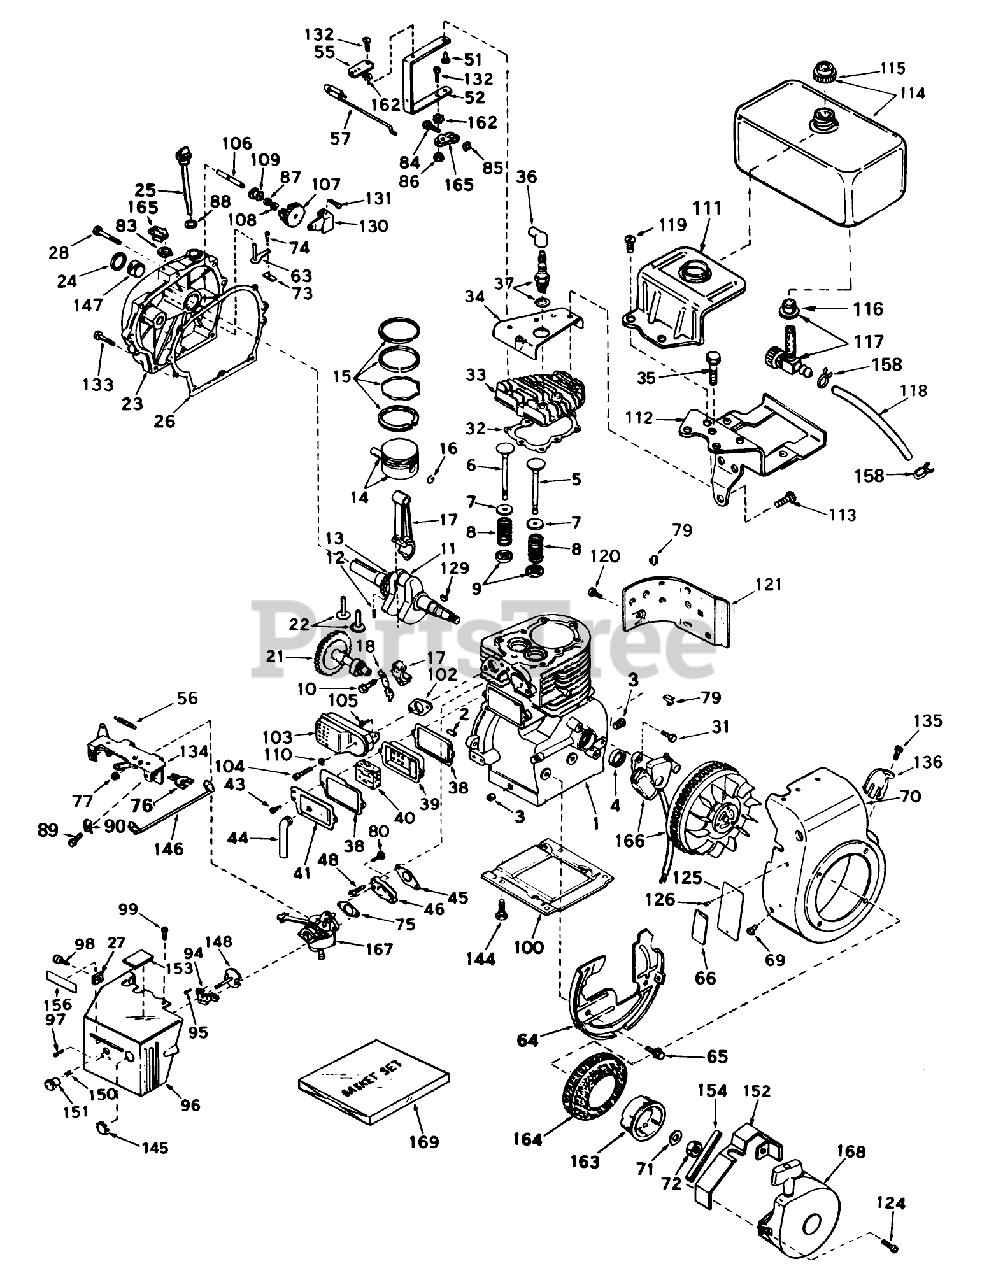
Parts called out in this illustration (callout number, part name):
1	Cylinder Assy. (Incl. Nos. 2, 3 4)
2	Pin-Dowel
3	Plug-Drain, Oil (SQH 1/4-18)
4	Oil Seal
5	Valve, Intake (Standard)(Incl. No. 9)
5	Valve, Intake (1/32" oversize)(Incl. No. 9)
6	Valve, Exhaust (Standard)(Incl. No. 9)
6	Valve, Exhaust (1/32" oversize)(Incl. No. 9)
7	Cap-Spring, Valve
8	Spring-Valve
9	Keeper-Spring, Valve
10	Screw, Hex Hd.
11	Crankshaft Assy. (Incl. Nos. 12 13)
12	Pin, Groove
13	Gear-Crankshaft
14	Piston Pin Assy. (Incl. 2 of No. 16)(Standard)
14	Piston Pin Assy. (Incl. 2 of No. 16)(.010 oversize)
14	Piston Pin Assy. (Incl. 2 of No. 16)(.020 oversize)
15	ORing
15	Ring Set (.010" OS)
15	Ring Set (.020" OS)
17	Rod Assy., Connecting (Incl. Nos. 10 18)
18	Plate, Lock
21	Camshaft
22	Lifter Valve
23	Cover, Cylinder (Incl. Nos. 24 106)
24	Oil Seal
25	Dipstick, Oil (Incl. No. 30)
26	Gasket-Cover, Cylinder
27	Nut-U Type
28	Screw (1/4-20 x 1-1/4)
31	Screw
32	Gasket-Cylinder Head
33	CYLINDER HEAD
34	Cover-Head, Cylinder
35	Screw Hex Hd. Cap
36	Cover-Spark Plug
37	Plug, Spark (J17LM or equiv.)
38	Gasket-Breather
39	Body-Breather
40	Element-Breather
41	Cover-Valve
43	Screw
44	Tube-Breather
45	Gasket-Intake
46	Flange, Carburetor (Incl. Nos. 77 80)
48	Screw
51	Rivet, Split
52	Lever, Governor
56	Spring, Extension
57	Link, Governor to Throttle
63	ROD ASSY, Governor
64	Baffle Blower Housing
65	Screw (1/4-20x19/32)
66	Decal, Instruction
69	Screw, Hex Hd.
70	Housing, Blower
71	Washer
73	Yoke-Governor
74	Screw (6-40x5/16)
75	Gasket-Carburetor
76	Terminal
77	Nut and Lock Washer (1/4-28)
79	51004 GIL ROTARY TI
80	Screw
83	Ring-Retaining
84	Screw
85	Nut-Lock
86	Nut-Lock
87	Washer-Flat
88	Gasket
89	Screw (10-32 x 3/8)
90	Conduit
94	Bracket-Choke
95	Screw (10-32 x 1/2)
96	Cover, Carburetor
97	Screw (8-32 X 5/16)
98	Screw (8-32 x 3/8)
99	Screw (10-32x1/2)
100	Base Engine
102	Gasket Exhaust
103	Muffler
104	Screw Hex Hd. Cap
105	Screw
106	Shaft-Governor
107	Governor Gear ASM
108	Ring-Retaining
109	Spool-Governor
110	Washer
111	Plate, Fuel Tank Mounting
112	Bracket, Fuel Tank
113	Screw (1/4-20x19/32)
114	Tank Assy., Fuel (Incl. Nos.115 117)
115	Cap, Fuel
116	Bushing, Fuel Fitting
117	Valve, Fuel Strainer Shut-off (Incl. No.116)
118	Line, Fuel
119	Screw, Fil, Slotted Hd. Sems
120	Screw
121	Emnsion, Blower Housing
124	Screw
125	IDENTIFICATION PLATE
126	DRIVE STUD
129	Key-Flywheel
130	Bracket, Governor
131	Screw (10-32 x 35/64)
132	Screw
133	Screw
134	Bracket Assy., Speed Control (Incl. No. 56)
135	Screw, Pan Hd.
136	Screw
144	Screw
145	Plug
146	Wire, Ground
147	Bushing-Crankshaft
148	Plate, Choke
150	Spring, Compression
151	Knob, Choke
152	Guard, Starter
153	Decal, Operating
154	Seal, Snowguard
156	Decal, Choke
158	Clamp-Line, Fuel
162	Washer-Lock
163	Cup-Starter
164	Screen, Air
165	Clamp-Lever, Governor
166	Magneto
167	Carburetor (Incl. No. 75)
168	Starter Assy., Rewind
169	Gasket Set
